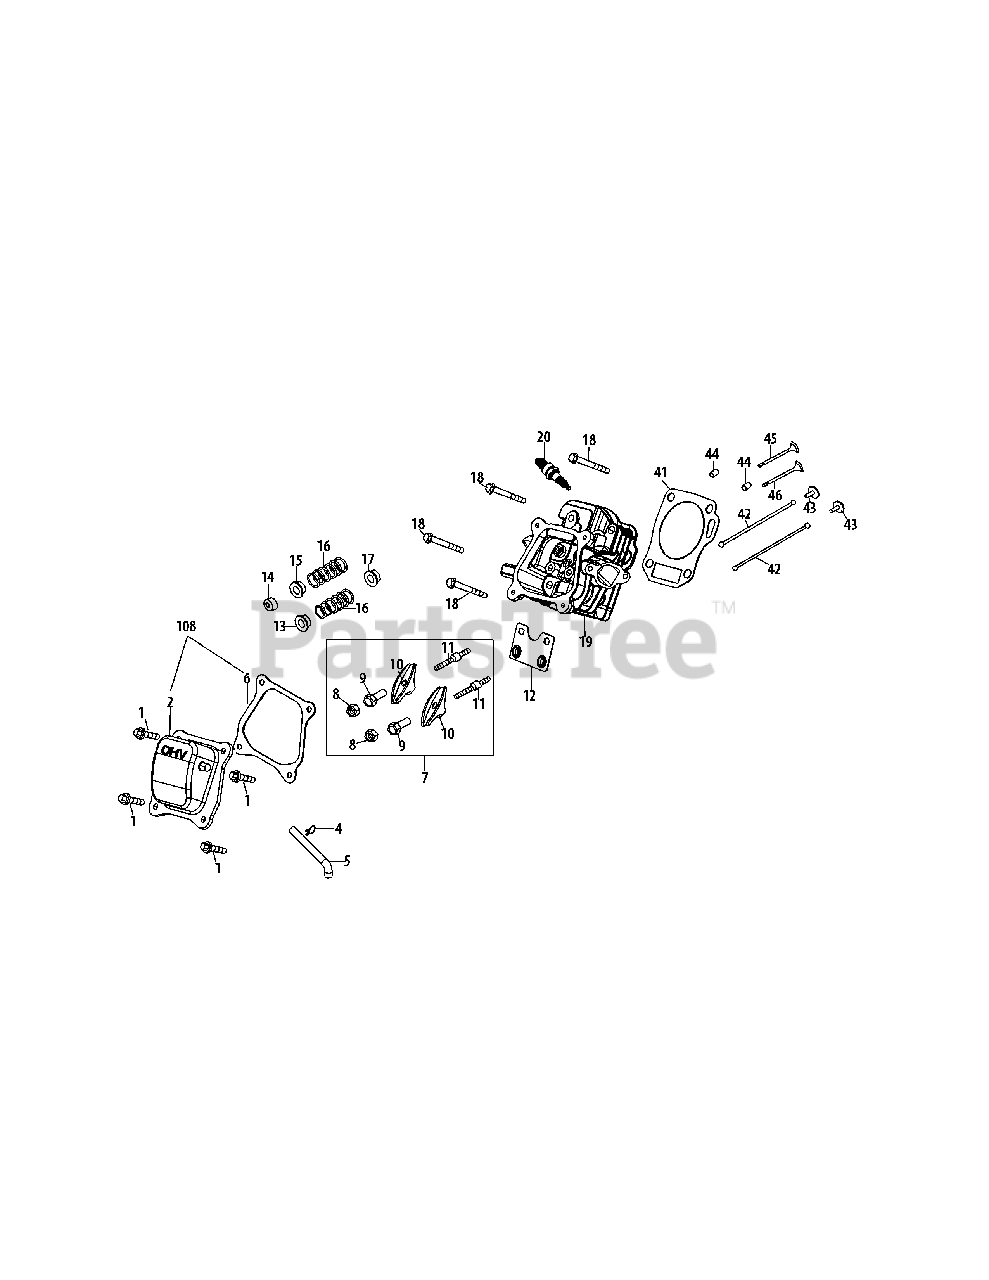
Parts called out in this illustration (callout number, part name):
1	Bolt M6×16
2	Valve Cover
4	Breather Hose Clamp
5	Breather Hose
6	Valve Cover Gasket
7	Rocker Arm Assembly
8	Nut, Pivot Locking
9	Adjusting Nut, Valve
10	Rocker Arm
11	Bolt, Pivot
12	Push Rod Guide
13	Retainer, In. Valve Spring
14	Adjuster, Ex. Valve
15	Retainer, Ex. Valve Spring
16	Valve Spring
17	Intake Valve Seal
18	Bolt M8×55
19	Cylinder Head Assembly
20	Spark Plug
41	Gasket, Cylinder Head
42	Push Rod Kit
44	Dowel Pin 10×16
108	Valve Cover Kit
